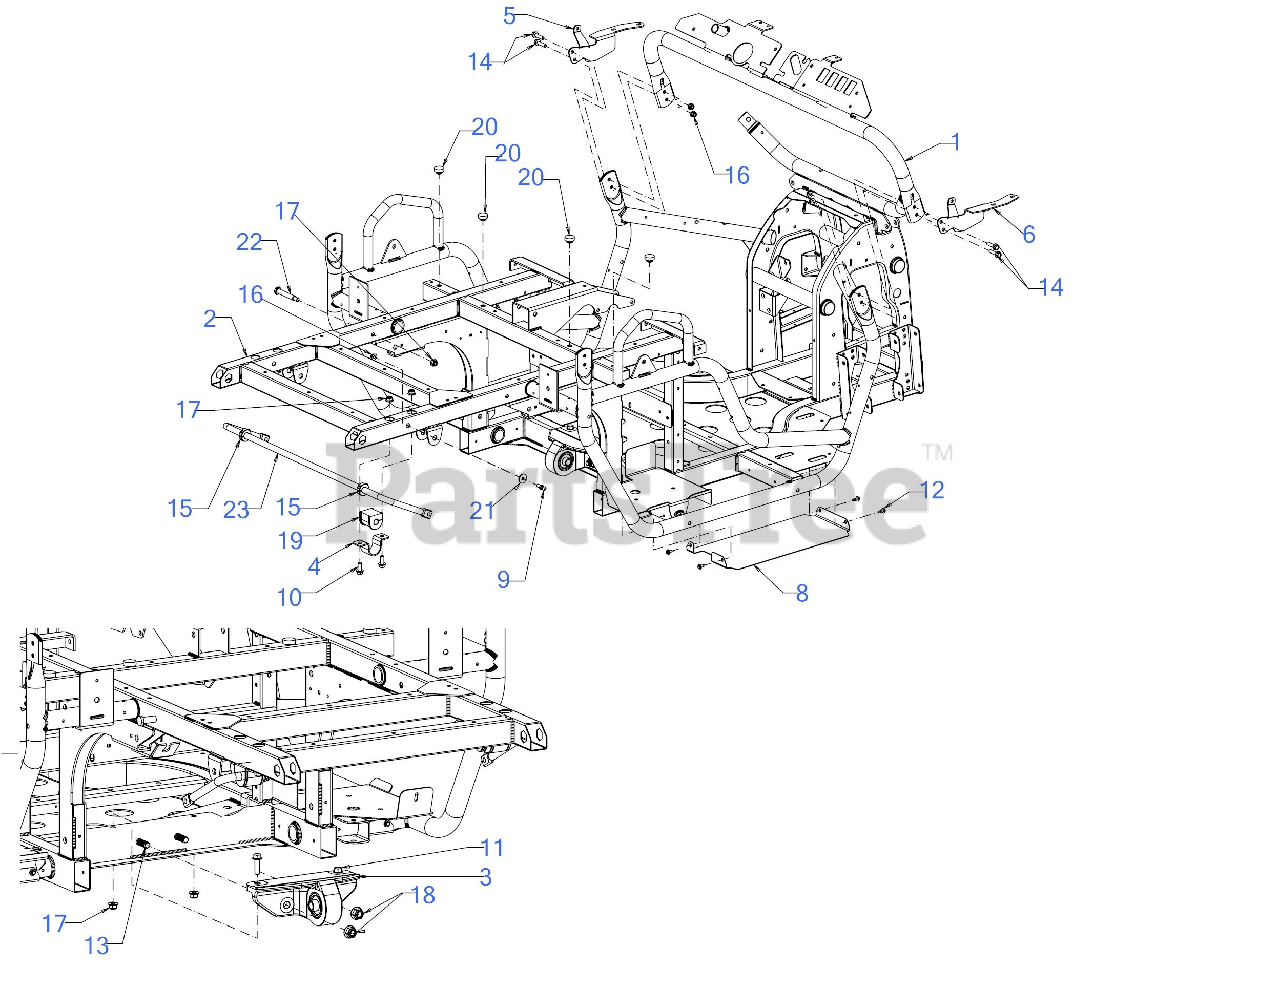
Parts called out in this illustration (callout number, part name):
1	DASH FRAME ASSEMBLY
3	SWING ARM PIVOT BEARING ASSEMBLY
4	SWAY BAR MOUNT
5	HOOD FRAME BRACKET (LH)
6	HOOD FRAME BRACKET (RH)
9	BALL STUD 5/16-18
10	SCREW 3/8-16 x .875 GR5
11	SCREW 3/8-16 x 1.25 GR5
12	SCREW M6-1 x .625
13	HEX FLANGE BOLT 1/2-13 GR8 LOCK
14	SCREW 5/16-18 x 1.25 GR5
15	SPLIT LOCKING COLLAR
16	FLANGE LOCK NUT 5/16-18
19	SWAY BAR BUSHING
20	RUBBER BUMPER 1.000 x .313
21	FLAT WASHER 1.0 OD:.331 ID
22	SHOULDER SCREW
23	UPPER SWAY ROD
